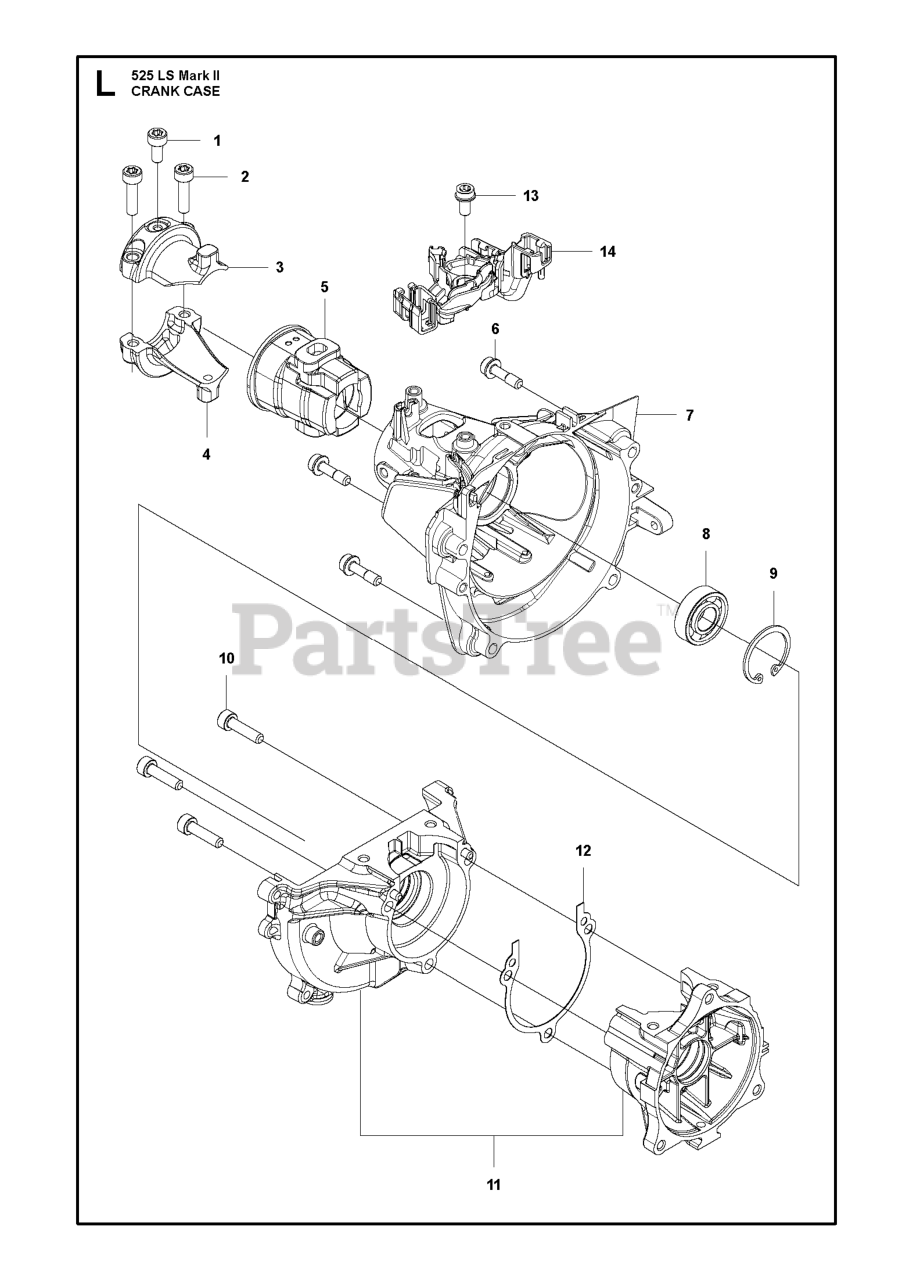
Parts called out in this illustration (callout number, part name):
2	BOLT M5X20 T27
3	BRACKET UPPER M5X0.8
4	BRACKET LOWER
5	CUSHION UPPER
6	BOLT
7	HOUSING CLUTCH
10	BOLT
11	CRANKCASE COMP
12	GASKET CASE
13	SCREW HEXALOBULAR SOCKET HEAD
14	HOLDER CONNECTIVITY DEVICE
